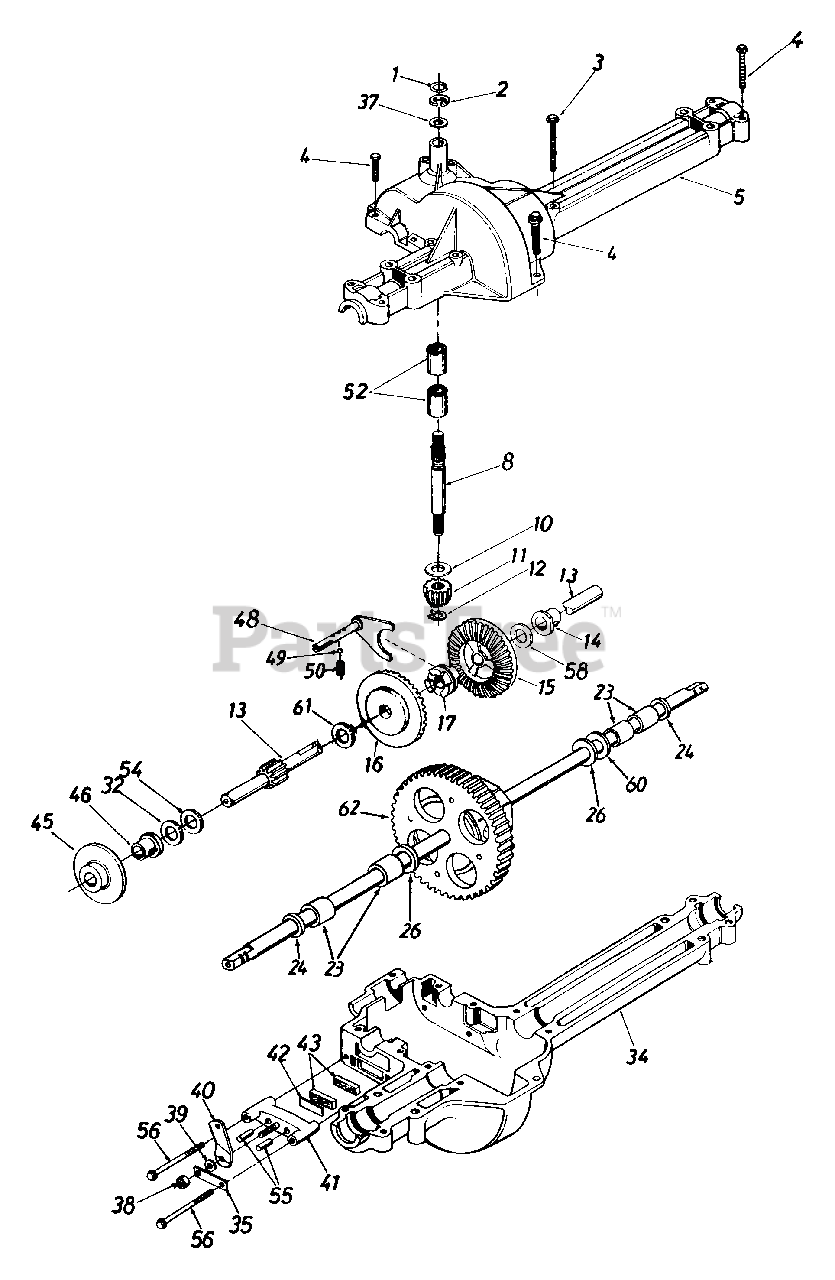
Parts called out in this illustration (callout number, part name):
1	Wire Ring
2	"E"-Ring
3	Hex Wash. TT-Tap 1/4 - 20 x 1.75" Lg.
4	Hex Tap Scr. 1/4 - 20 x 1.25" Lg.
5	Upper Housing
8	Input Shaft
10	Thrust Washer 5/8" I.D. x 1.25" 0 D.
11	Pinion Input 14T
12	Retaining Ring
13	Drive Shaft - L.H. Brake
14	Flange Brg. 5/8" I.D. x 3/4" Lg.
15	Bevel Gear 42T - Small I.D.
16	Bevel Gear 42T - Large I.D.
17	Clutch Collar
21	Pan Head Scr. 1/4 - 20 x .50" L.g. w/Patch
23	Sleeve Bearing 3/4" I.D. x 1.0" Lg.
24	Oil Seal 3/4" I.D.
26	FL-Wash. .760" I.D. x 1.5" O.D.
32	Washer
34	Lower Housing
35	Anti-Rotation Brkt.
37	Washer
38	Hex Nut 5/16 - 24 Thd.
39	FL-Wash. .344" I.D. x .875" O.D.
40	Actuating Arm
41	Brake Yoke
42	Puck Plate
43	Brake Puck
45	Brake Disc
46	Flange Bearing 5/8" I.D. x 15/16" Lg.
48	Shift Fork Ass'y.
49	Ball Detent .250" Dia.
50	Spring Detent
52	Needle Brg. 5/8" I.D. x 1/2" Lg.
54	FL-Wash. 5/8" I.D. x 1" O.D. x .020 Thk.
55	Actuating Pin 5/16" Dia.
56	Hex Wash Hd. Self-Tap Scr. 1/4 - 20 Thd.
58	FL-Wash. 5/8" 1.D. x 1" O.D. x .020 Thk.
60	Washer
61	Thrust Washer
62	Differential Ass'y.
